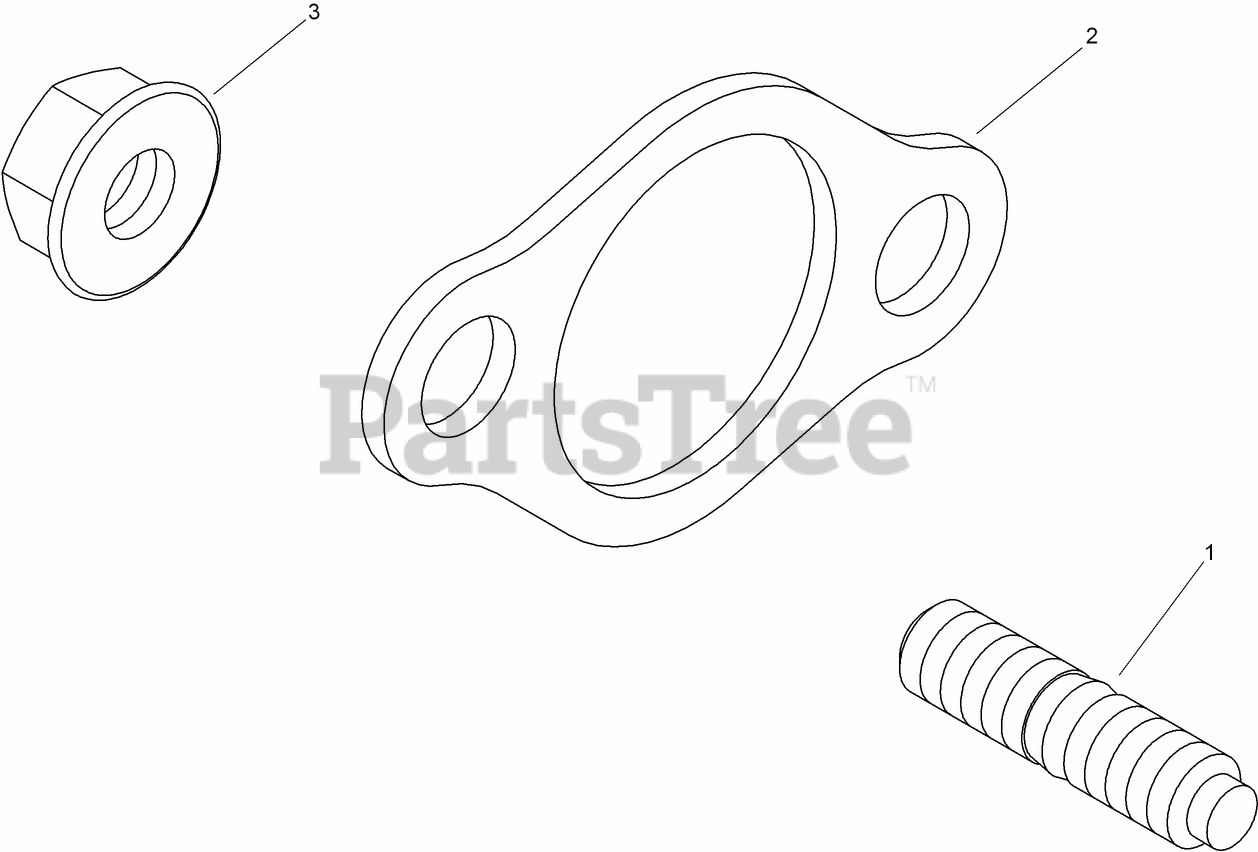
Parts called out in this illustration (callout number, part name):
1	STUD (M8X1.25X33)
2	GASKET-EXHAUST
3	NUT-FLANGE (M8X1.25)
